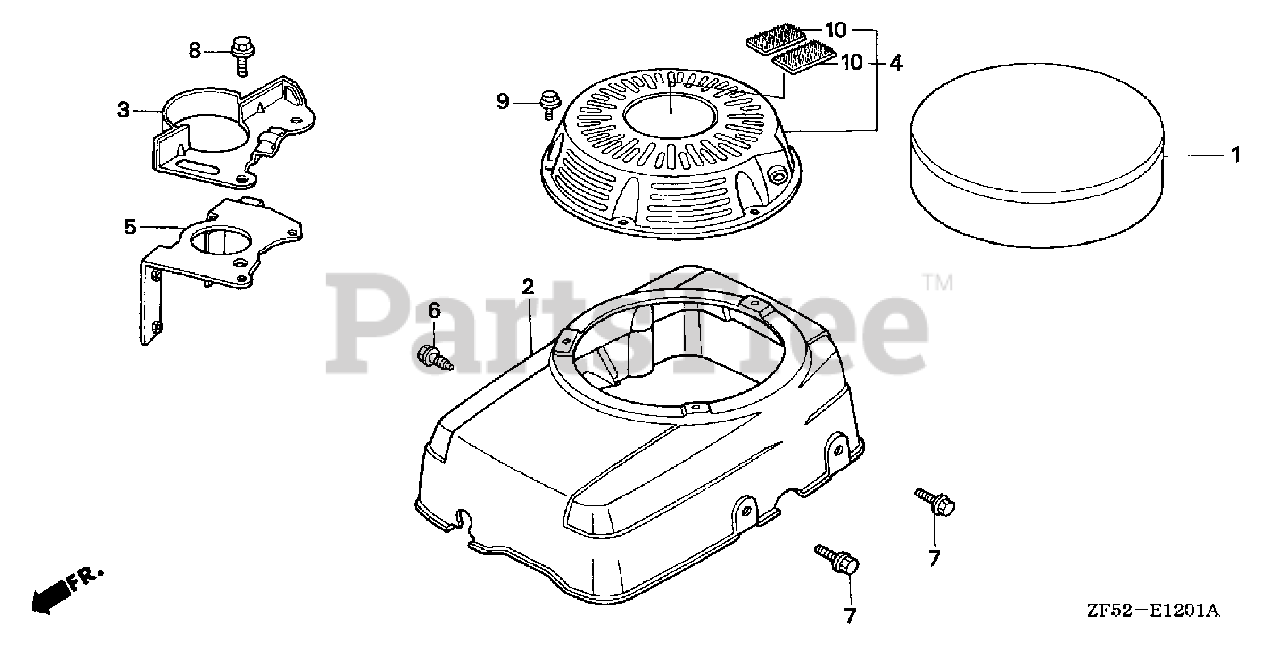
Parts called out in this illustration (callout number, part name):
2	COVER, FAN *R280* (POWER RED)
3	PLATE, SIDE
5	STAY, STARTER
6	BOLT, FLANGE (6X12) (CT200)
7	BOLT, FLANGE (8X16)
8	BOLT, FLANGE (8X28)
